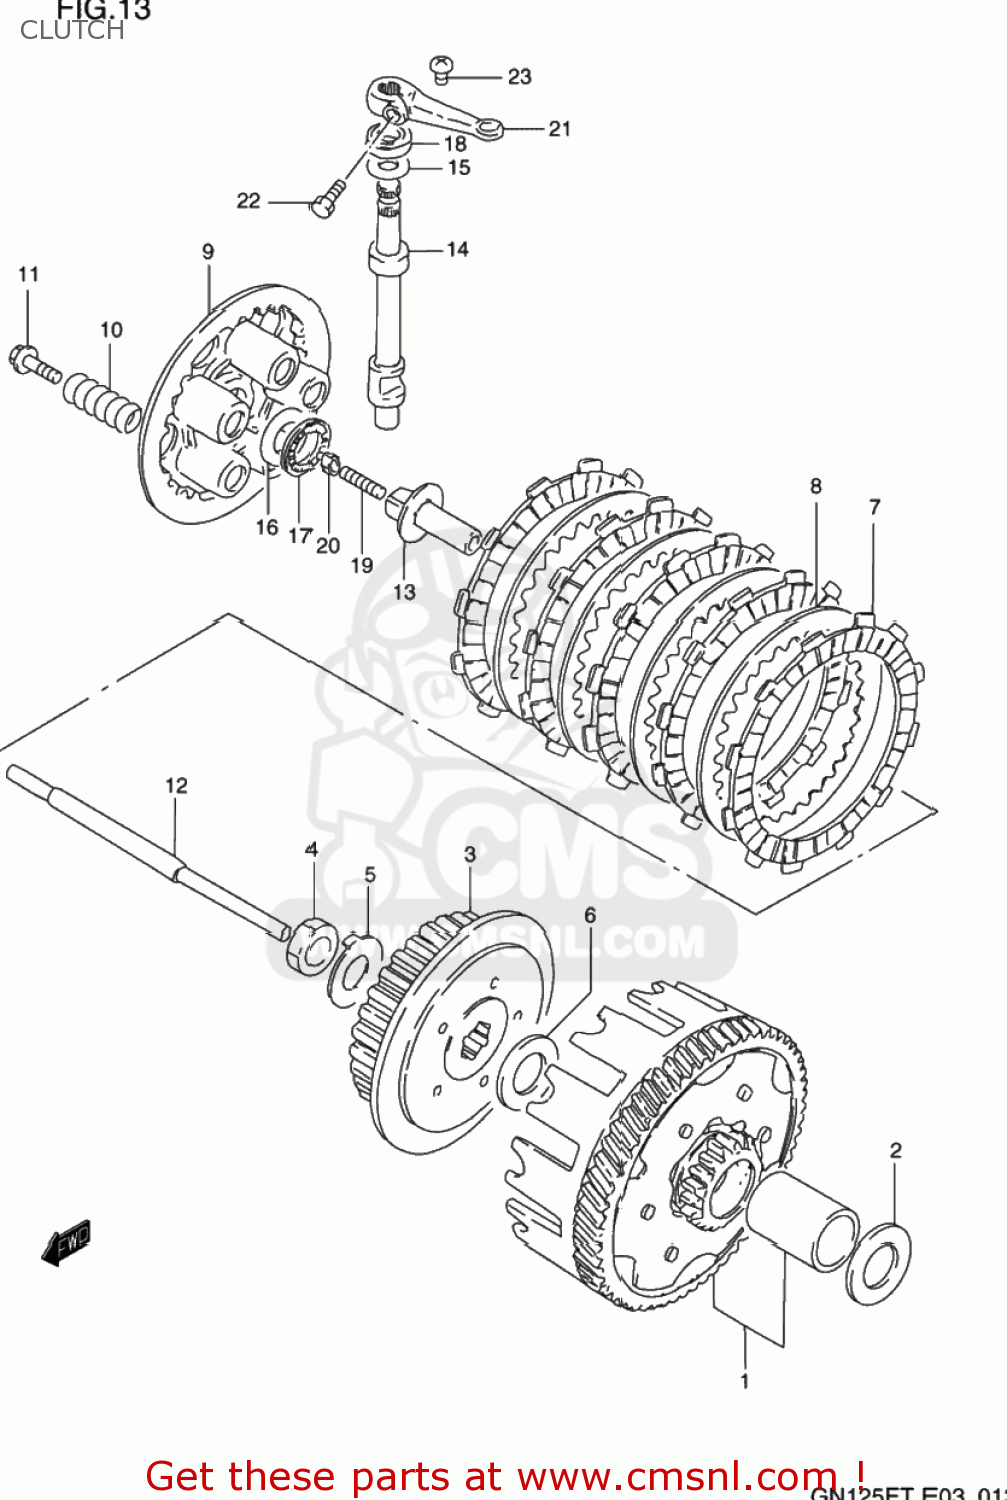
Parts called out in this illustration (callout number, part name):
1	GEAR ASSY,PRI DRIVEN(NT:59)
2	WASHER
3	HUB,CLUTCH SLEEVE
4	NUT
5	WASHER
6	WASHER
7	PLATE,CLUTCH DRIVE (NAS)
8	PLATE,CLUTCH DRIVEN (NAS)
9	PLATE,CLUTCH PRESSURE
10	SPRING
11	BOLT 5X16
12	ROD,CLUTCH PUSH
13	PIECE,CLUTCH PUSH
14	CAMSHAFT,CLUTCH RELEASE
15	WASHER,THRUST
16	WASHER
17	BEARING(15X28X2)
18	OIL SEAL
19	SCREW(6X25)
20	NUT
21	ARM,CLUTCH RELEASE
22	BOLT
23	SCREW
